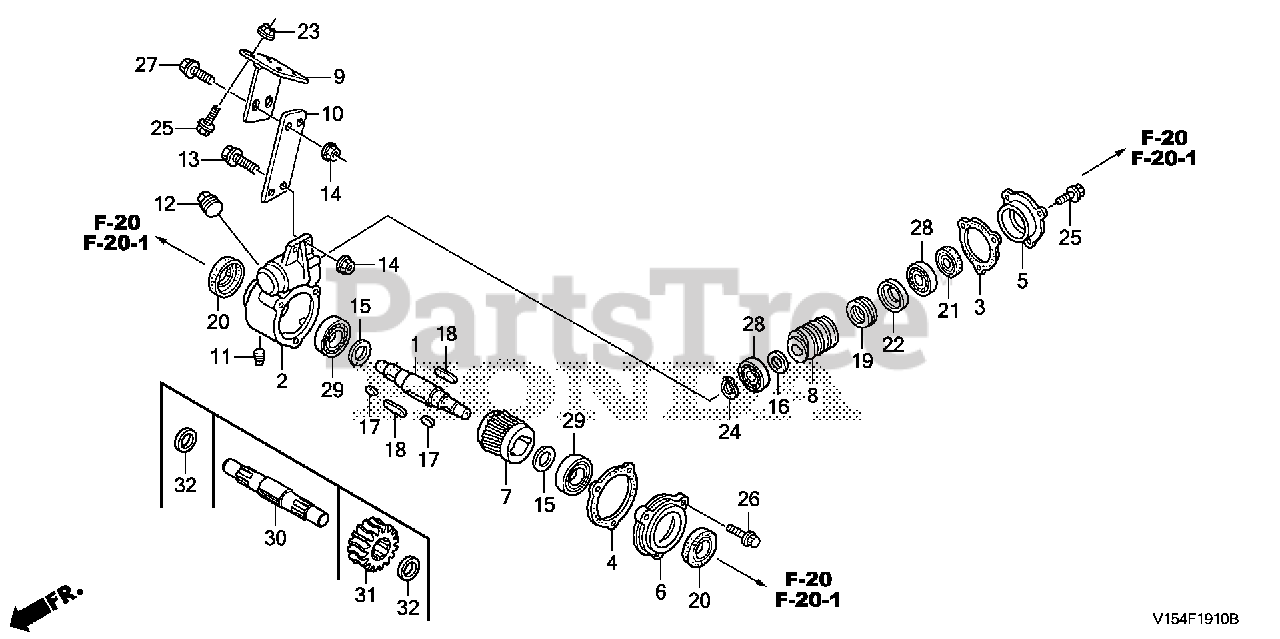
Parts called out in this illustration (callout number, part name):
2	CASE, AUGER TRANSMISSION
3	GASKET A, AUGER TRANSMISSION
4	GASKET B, AUGER TRANSMISSION
5	COVER A, AUGER TRANSMISSION
6	COVER B, AUGER TRANSMISSION
8	GEAR, DRIVE
9	BRACKET A, AUGER HOUSING
10	BRACKET B, AUGER HOUSING
11	BOLT, DRAIN PLUG (PT 1/8)
12	BOLT, DRAIN PLUG (PT 3/4)
13	BOLT, RR. DAMPER (UPPER)
14	NUT, SELF-LOCK (10MM)
16	WASHER (20X29X2)
19	BEARING, THRUST (51204)
20	OIL SEAL (30X45X8)
21	OIL SEAL (25X38X7)
21	OIL SEAL (25X38X7) (ARAI)
22	COLLAR, THRUST
23	NUT, FLANGE (8MM)
24	CIRCLIP (OUTER) (20MM)
25	BOLT, FLANGE (8X20) Use up to Engine SN 1609606.
26	BOLT, FLANGE (8X25)
27	BOLT, FLANGE (10X22)
28	BEARING, RADIAL BALL (6004)
29	BEARING, RADIAL BALL (6006)
30	SHAFT, AUGER
31	GEAR, DRIVEN (20T)
32	COLLAR (30X44X14)
